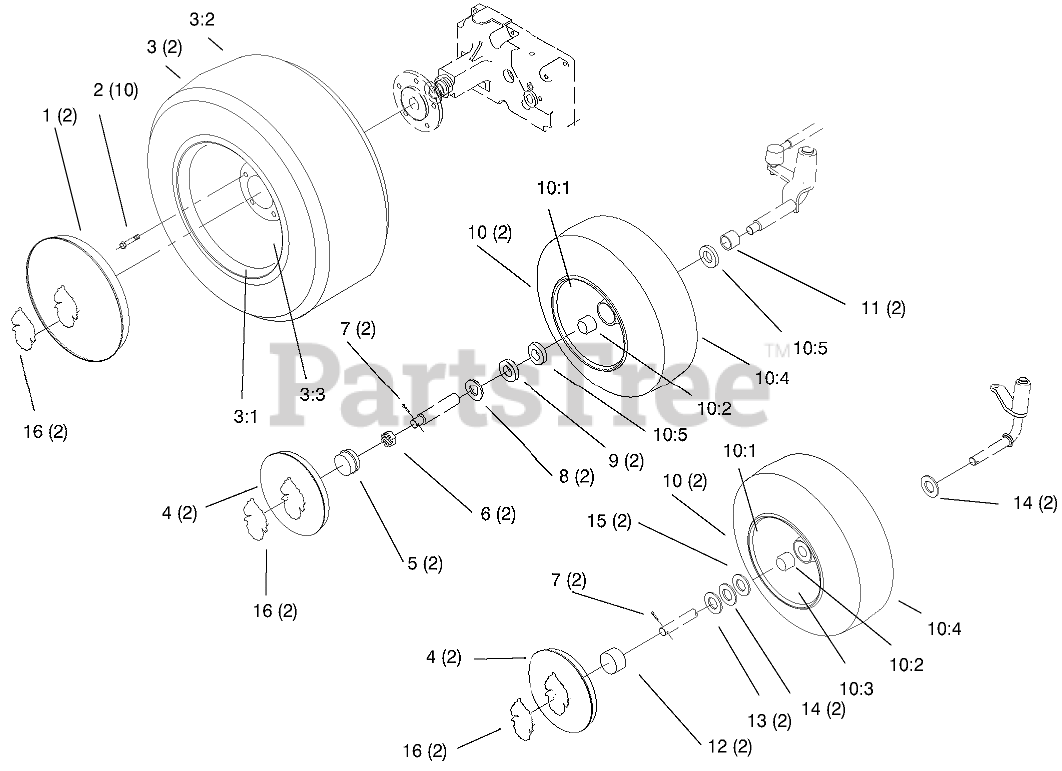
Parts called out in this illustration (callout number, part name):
1	HUBCAP - 12"
2	BOLT-LUG
3	ASM-Wheel & Tire
3:1	WHEEL
3:2	TIRE
3:3	VALVE
4	HUBCAP - 8"
7	PIN-COTTER
10	FRONT WHEEL ASM
10:1	ASS'Y-WHEEL
10:2	Bearing
10:3	VALVE
10:4	TIRE-16 X 7.50 TURF
10:5	SEAL-OIL
12	HUBCAP
13	WASHER WHEEL
14	WASHER
15	WASHER-SHIM
16	LOGO (GOLD)
